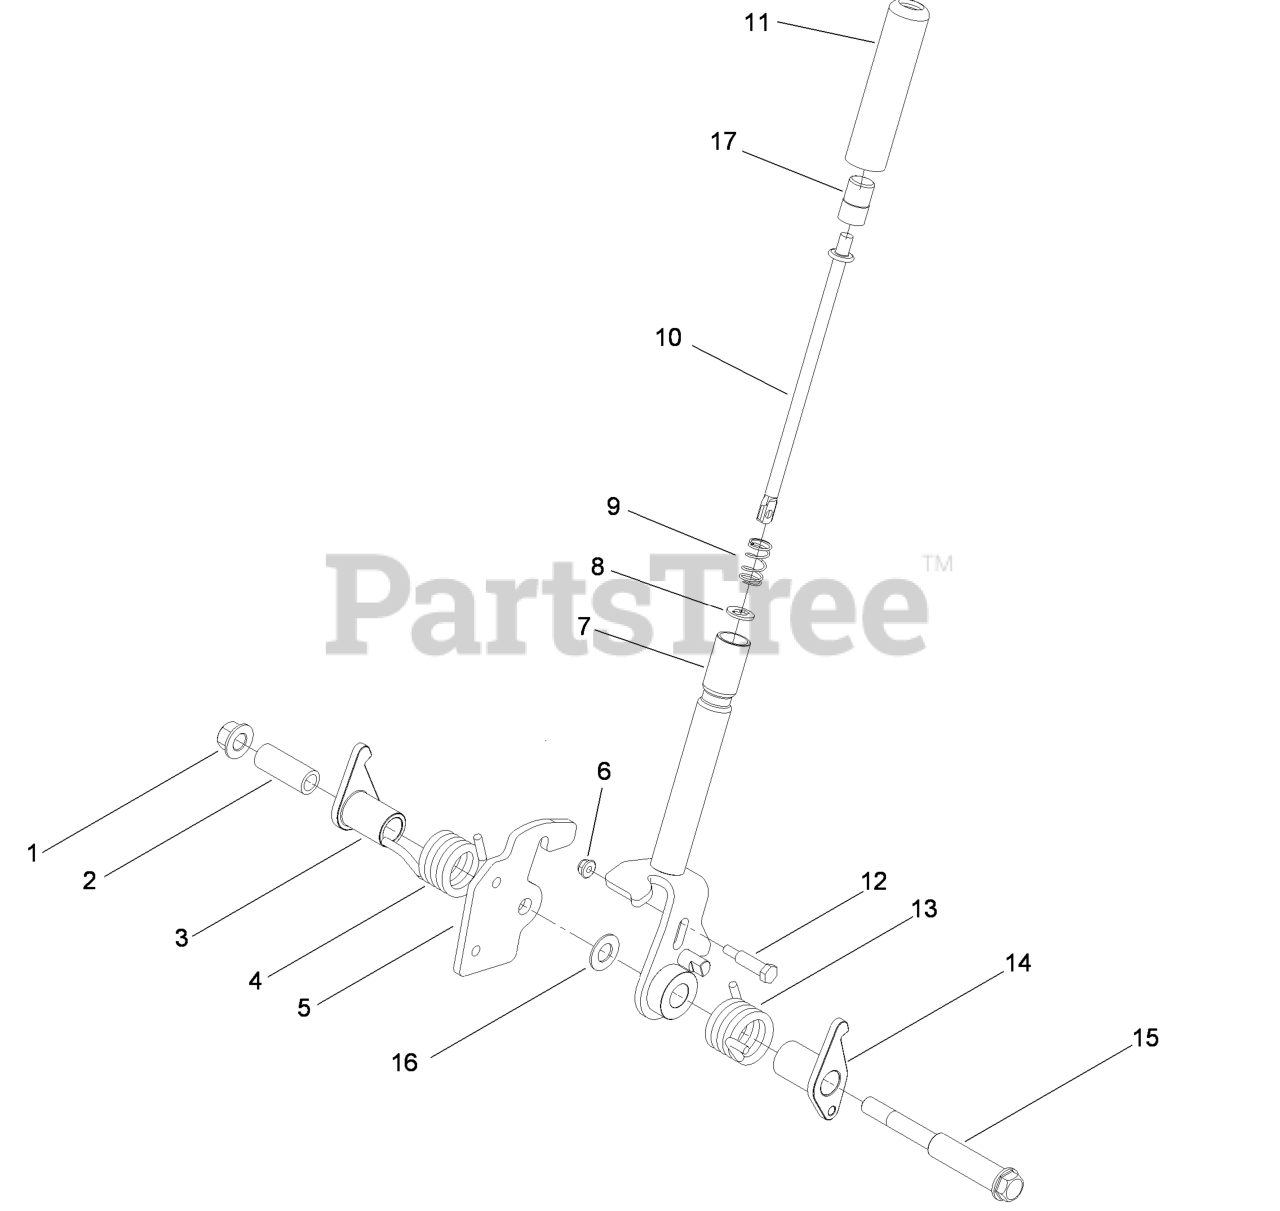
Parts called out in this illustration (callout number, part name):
1	Nut-Lock 1/2-13
3	ARM-BRAKE, LH
4	SPRING-TORSION, RH
5	PLATE-LATCH
7	BRAKE HANDLE ASM
8	WASHER-SPECIAL
9	SPRING-COMPRESSION
10	ROD-RELEASE, BRAKE
12	BOLT-SHOULDER
13	SPRING-TORSION, LH
14	ARM-BRAKE, RH
15	BOLT-SHOULDER
16	WASHER-FLAT
